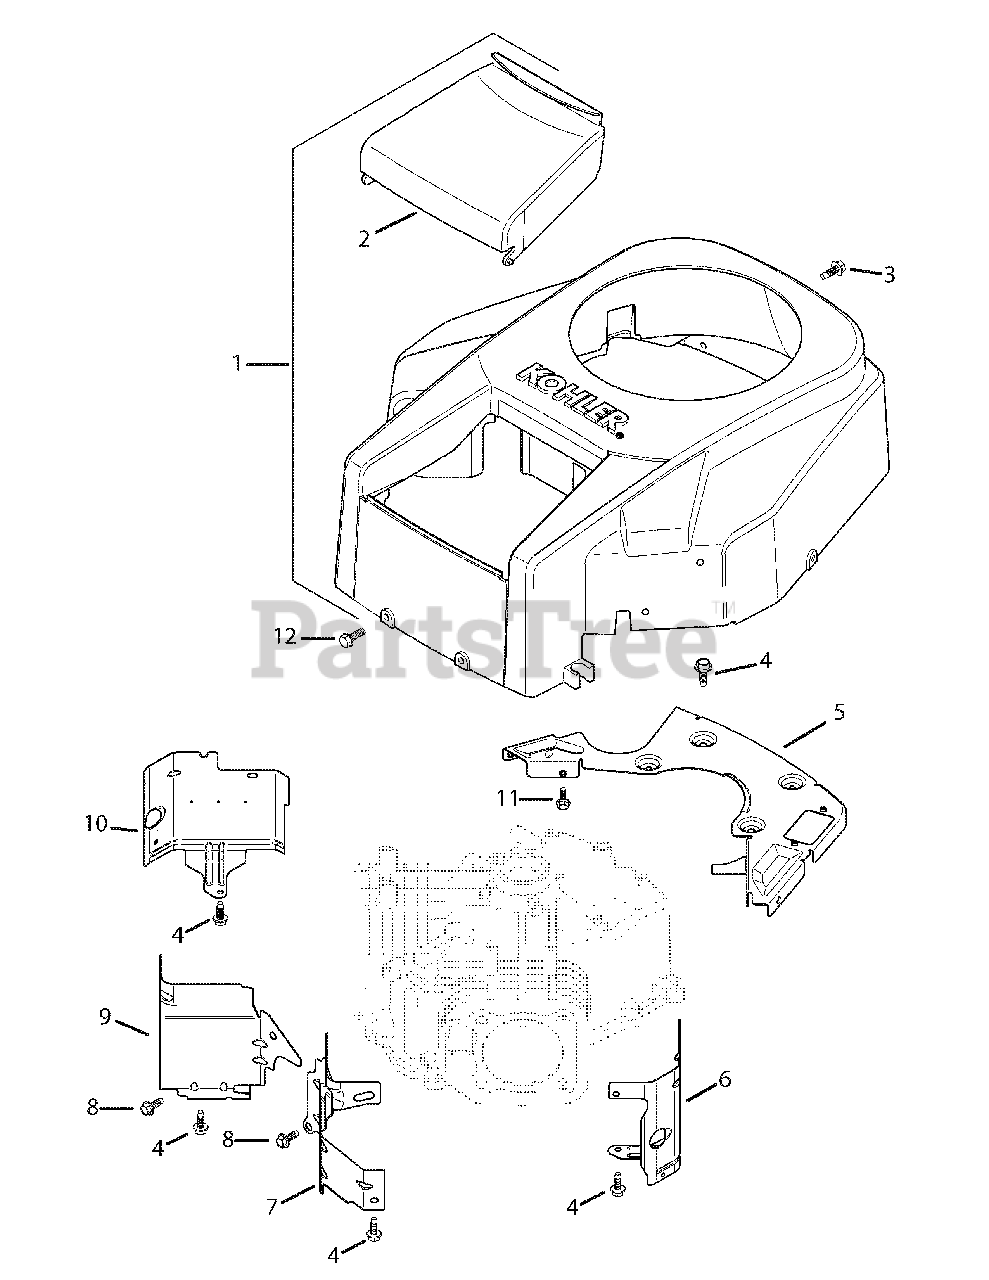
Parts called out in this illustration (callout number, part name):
1	Housing, blower
2	Cover, air cleaner
3	Screw, hex. flange M5x0.8x16
4	Screw, hex. flange M6x1.0x16
5	Plate, backing w/rectifier-regulator opening
6	Baffle, cylinder barrel - #2 side
7	Baffle, valley - #2 side
8	Screw, hex. flange M5x0.8x10
9	Baffle, valley - #1 side
10	Baffle, cylinder barrel-#1 side
11	Screw, hex. flange M5x0.8x20
12	Screw, hex. cap M6x1.7x18
